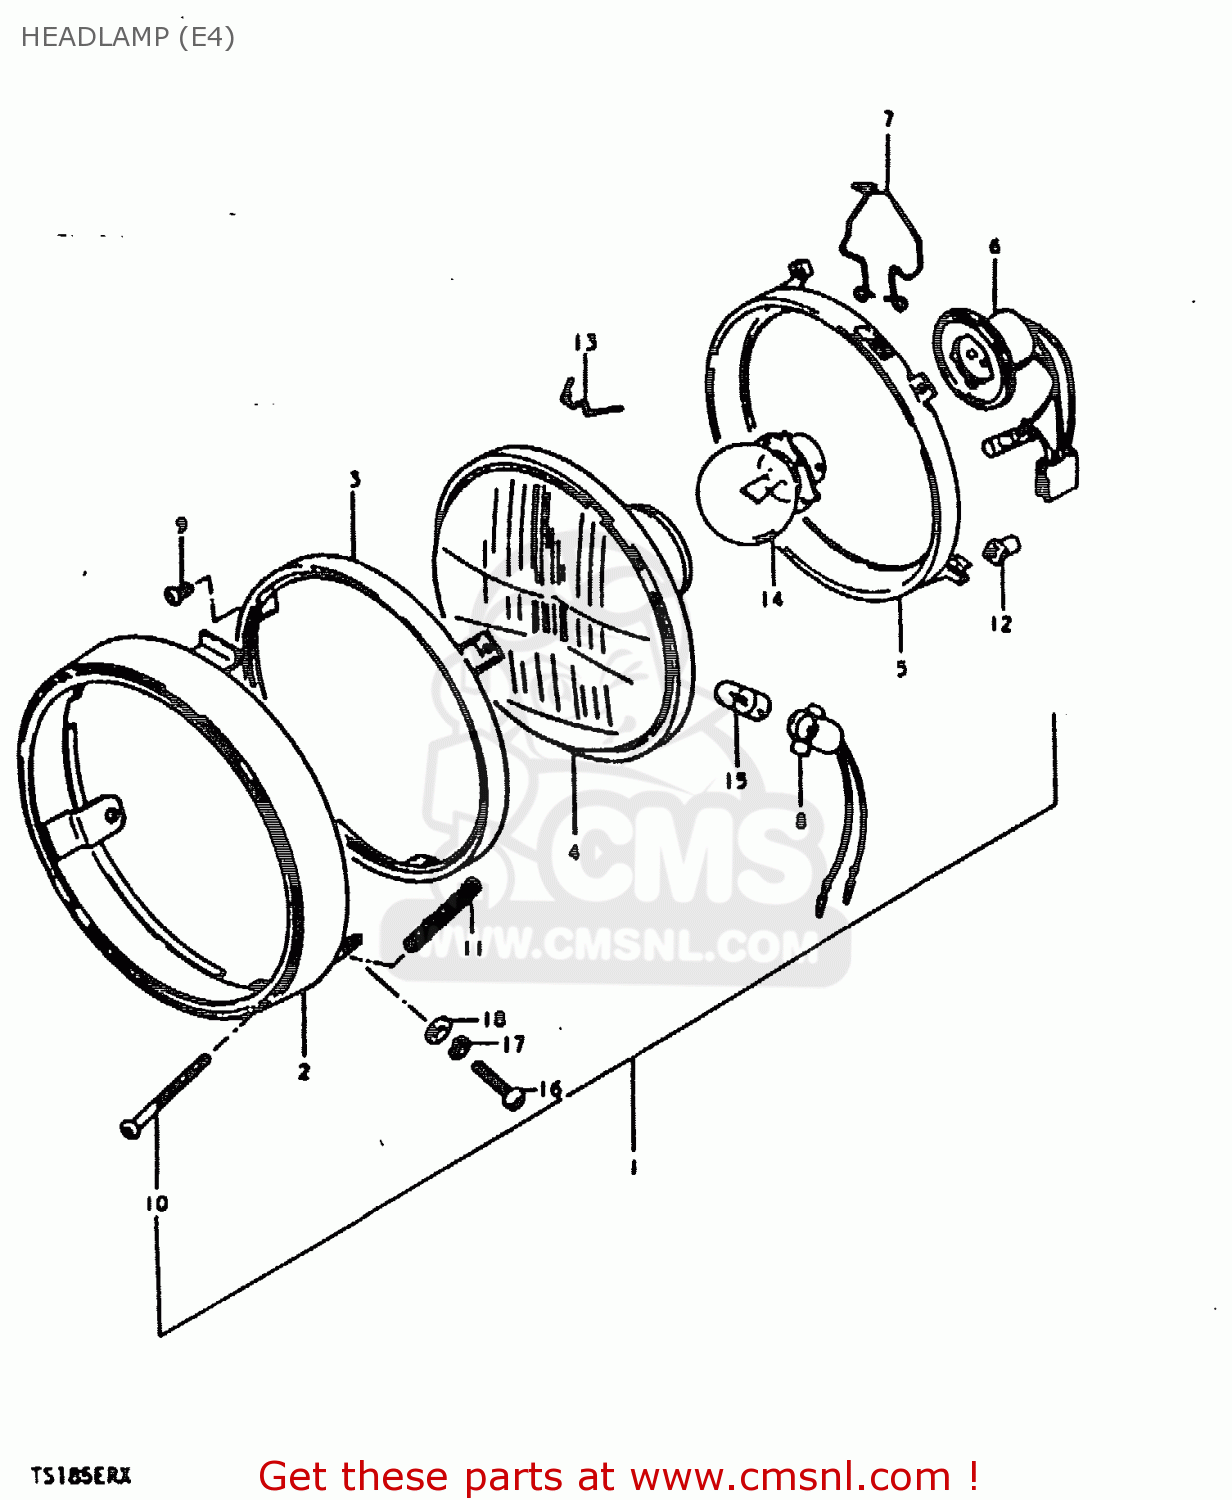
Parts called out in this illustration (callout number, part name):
1	HEADLAMP ASSY
2	RIM
3	RETAINER,HEADLAMP
4	UNIT
5	RING, MOUNTING
6	SOCKET
7	CLAMP,HEADLAMP
8	SOCKET
9	SCREW
10	SCREW,HEADLAMP ADJUST
11	SPRING,ADJUSTING
12	NUT,HEADLAMP ADJUSTER
13	SPRING,HEADLAMP UNIT
14	BULB (6V,25/25W)
15	BULB(6V4W,STANLEY,A1364J)
16	SCREW
17	LOCK WASHER
18	WASHER
